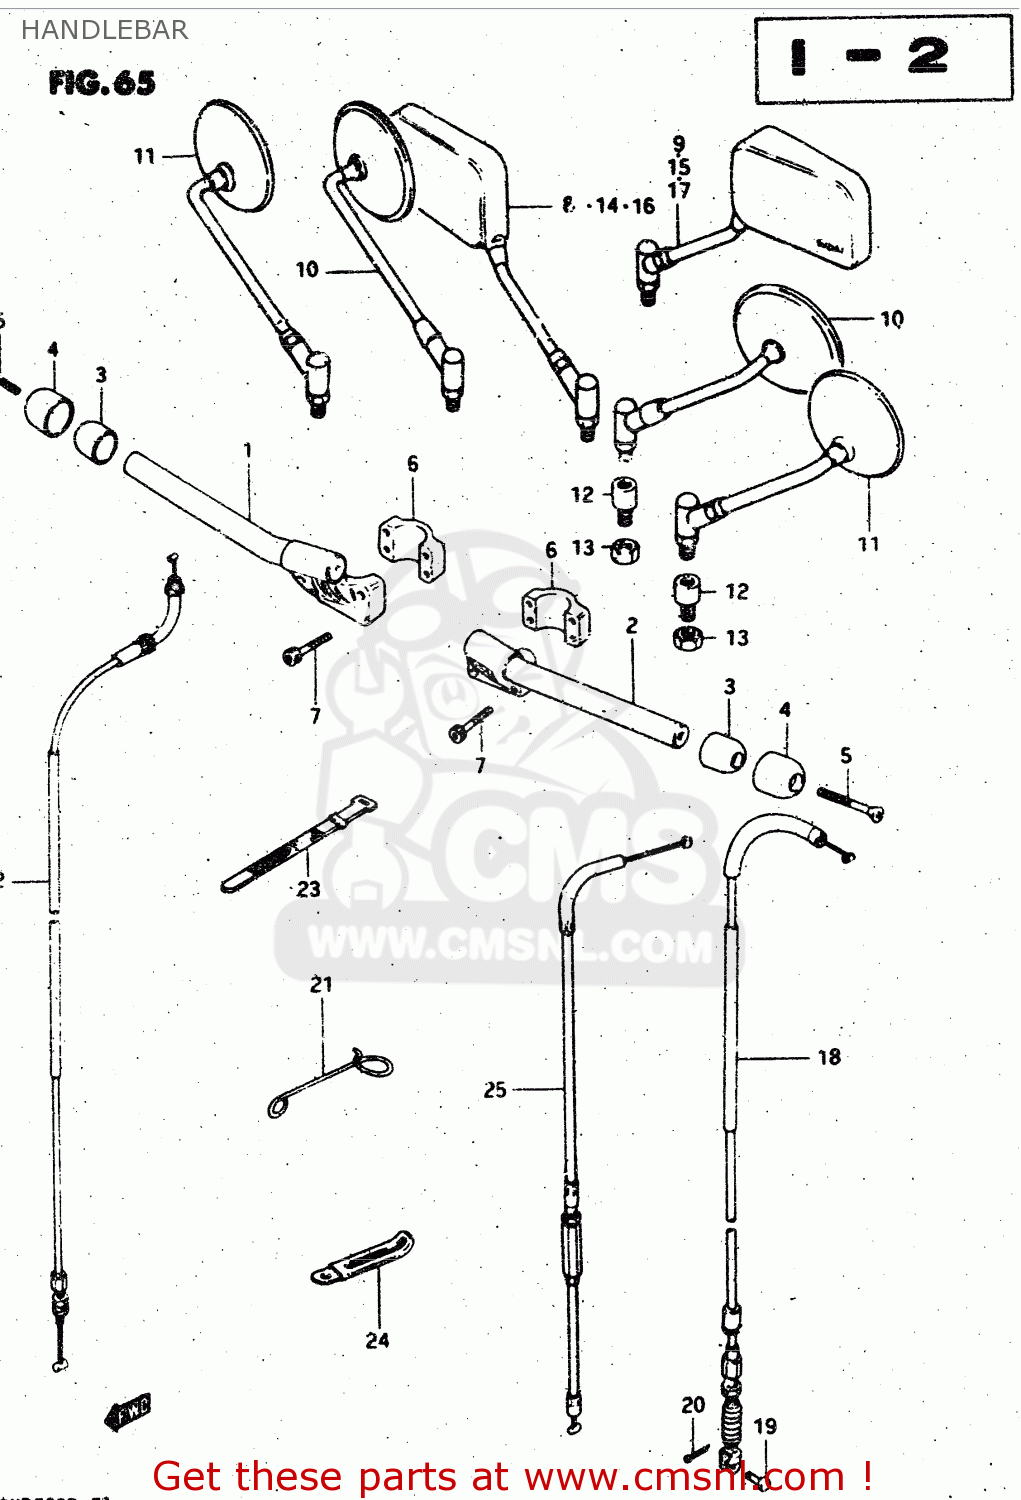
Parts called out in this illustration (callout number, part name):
1	HANDLEBAR,R
2	HANDLEBAR,L
3	BALANCER,HANDLEBAR
4	CAP,HANDLE BALANCER
5	SCREW 6X55
6	HOLDER,HANDLEBAR
7	BOLT
8	MIRROR ASSEMBLY,REAR VIEW
9	MIRROR ASSEMBLY,REAR VIEW
10	MIRROR ASSY,RH
11	MIRROR ASSY,RH
12	CUSHION,REAR VIEW MIRROR
13	NUT
14	MIRROR, REAR VIEW RH
15	MIRROR ASSY,LH
16	MIRROR, REAR VIEW RH
17	MIRROR, REAR VIEW LH
18	CABLE ASSY,CLUTCH
19	PIN(L:15)
20	PIN
21	GUIDE,CLUTCH CABLE
22	CABLE ASSEMBLY,THROTTLE
23	CLAMP(L:80)
24	CLAMP
25	CABLE,CLUTCH
